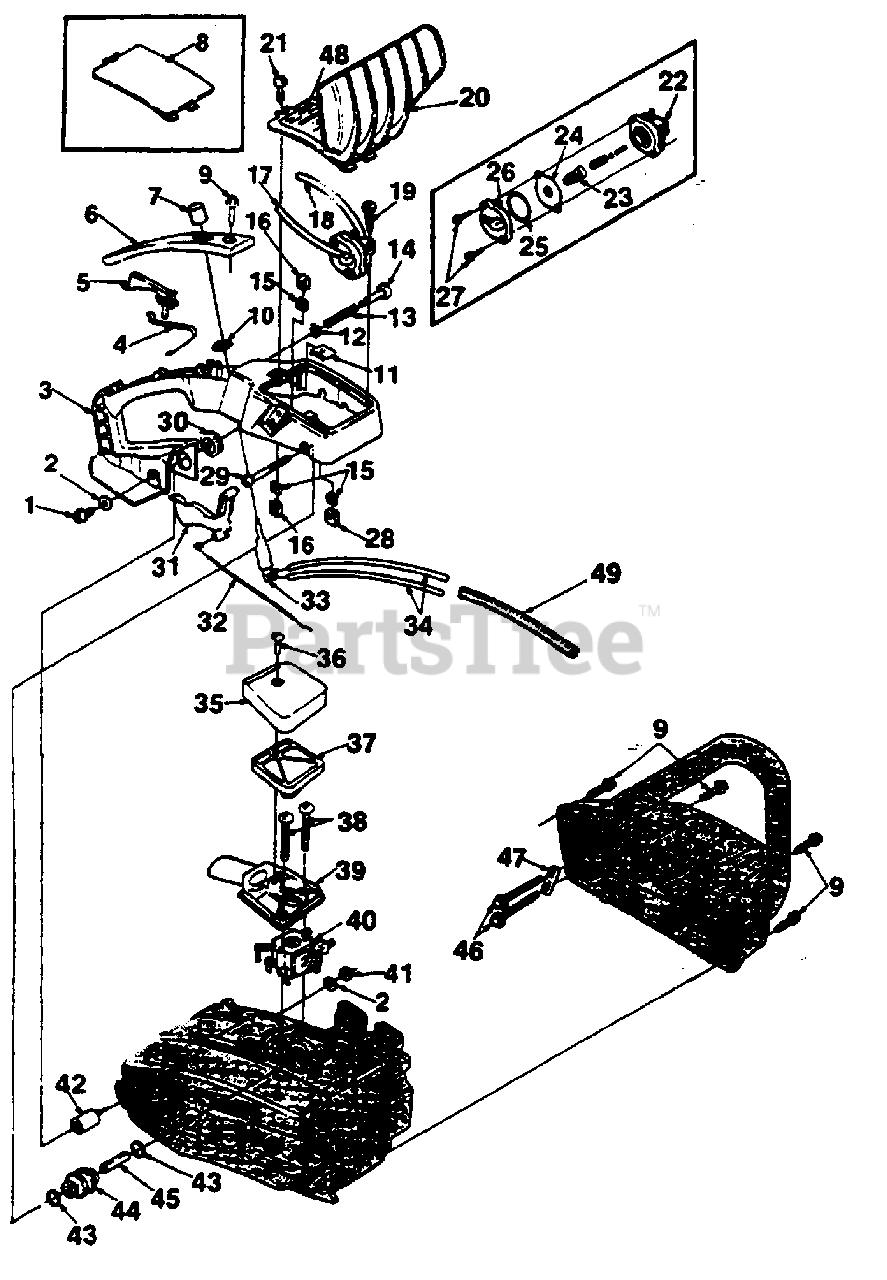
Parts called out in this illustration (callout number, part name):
1	SCREW- 10-32 x 3/8
2	WASHER- Flat #10
3	CHAMBER- Carburetor
4	SPRING- Throttle lock
5	INTERLOCK- Trigger
6	COVER- Handle
7	BUTTON- Oil pump
8	COVER- Air filter (245 SL only)
9	SCREW- #10 x 3/4
10	NUT- Hex (15/32 x 32)
11	NUT- Speed
12	RING- Retaining
13	SPRING- Compression
14	PIN- Throttle lock
15	NUT- Square 10-24
16	RETAINER- Nut
17	LINE- Pulse 3 1/4"
18	TUBING- (Oil outlet) 4 1/2" (Auto)
19	SCREW- Plastic #10 x 5/8
20	GUARD- Hand (w/cover) (245HG only)
21	SCREW- Retaining
22	BODY- Oil pump
23	SPRING- Oil pump
24	PLUNGER- Oil pump
25	"O" RING
26	COVER- Oil pump
27	SCREW- Plastite #8-16 x 5/8
28	RETAINER- Nut
29	SCREW- Soc. hd. cap( 10-24 x 1 5/8)
30	GROMMET
31	TRIGGER- Throttle
32	CABLE- Control
33	PUMP- Manual oil
34	TUBING- 6 3/4"
35	COVER- Air filter
36	SCREW- Retaining
37	FILTER- Air
38	SCREW- Mach/hex 10-24 x 1 5/8
39	BASE- Air filter
40	CARBURETOR- (Zama CIS-H8)
41	NUT- Lock hex (10-24)
42	ISOLATOR- Shear
43	RING- Vibration isolator
44	ISOLATOR
45	SPACER-
46	SCREW- Hex (10-24 x 1 1/8)
47	PLATE- Handle bar
48	DECAL- Warning
